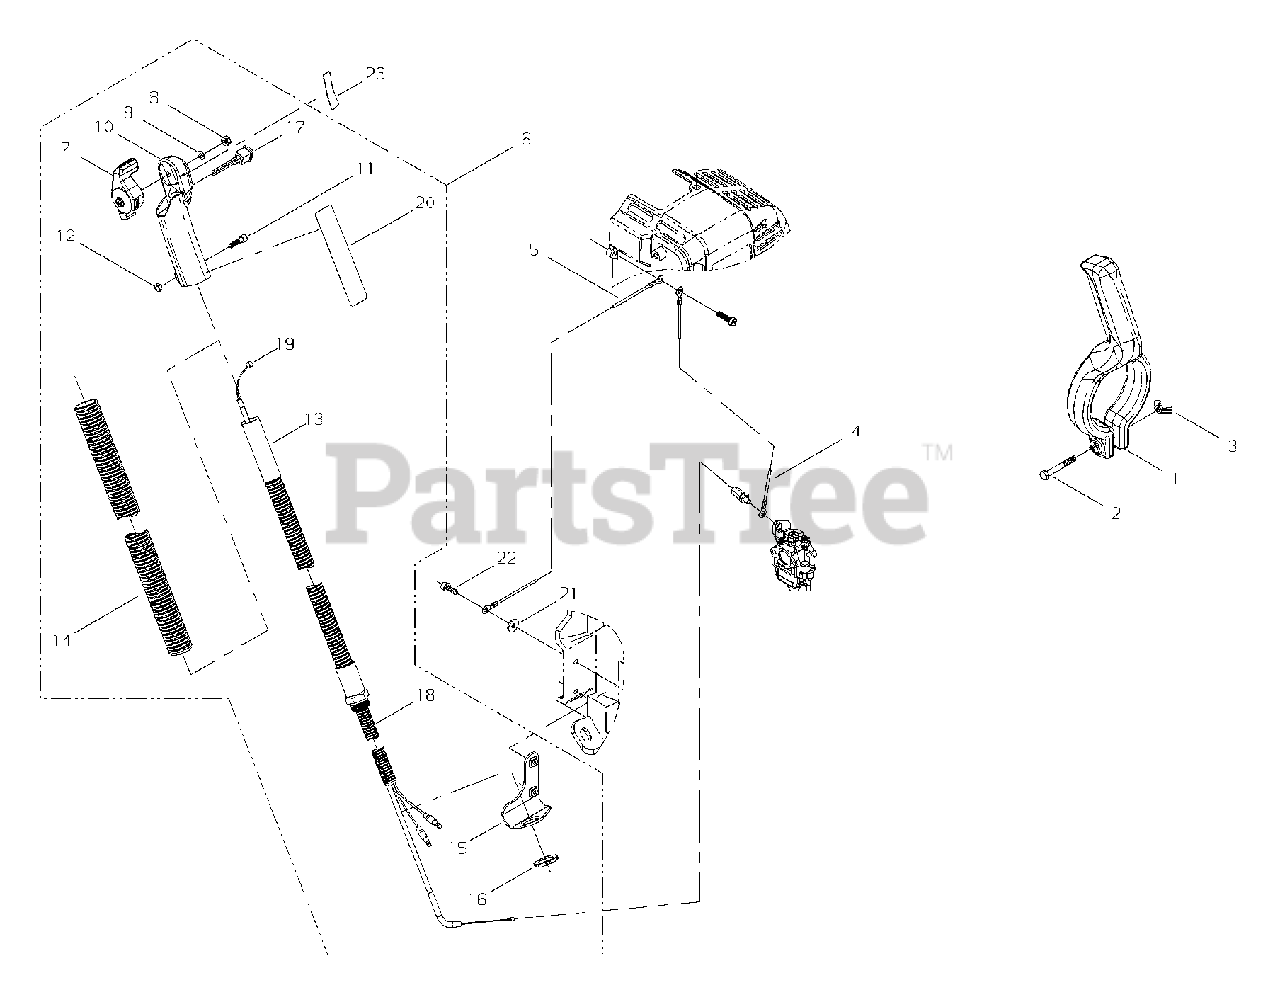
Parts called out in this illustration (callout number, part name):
1	HANDLE
2	BOLT 6×45
3	NUT, WING M7
4	WIRE, STATIC DISCHARGE 110 MM
5	LEAD 0.75 MM2 L= 590
6	THROTTLE CONTROL ASSY
7	CONTROL, THROTTLE
8	U-NUT M5
9	WASHER 5 MM
10	GRIP
11	BOLT M5×16
12	NUT M5
13	ARM, FLEX
14	TUBE, OUTER FLEX
15	BRACKET, MOUNTING
16	NUT
17	SWITCH, ON-OFF
18	TUBE, FLEXIBLE
19	CABLE, THROTTLE
20	PLATE, GROUND
21	WASHER Ø15ר5.2×1.6
22	BOLT, ADHESIVE M5×18
23	LABEL, THROTTLE
